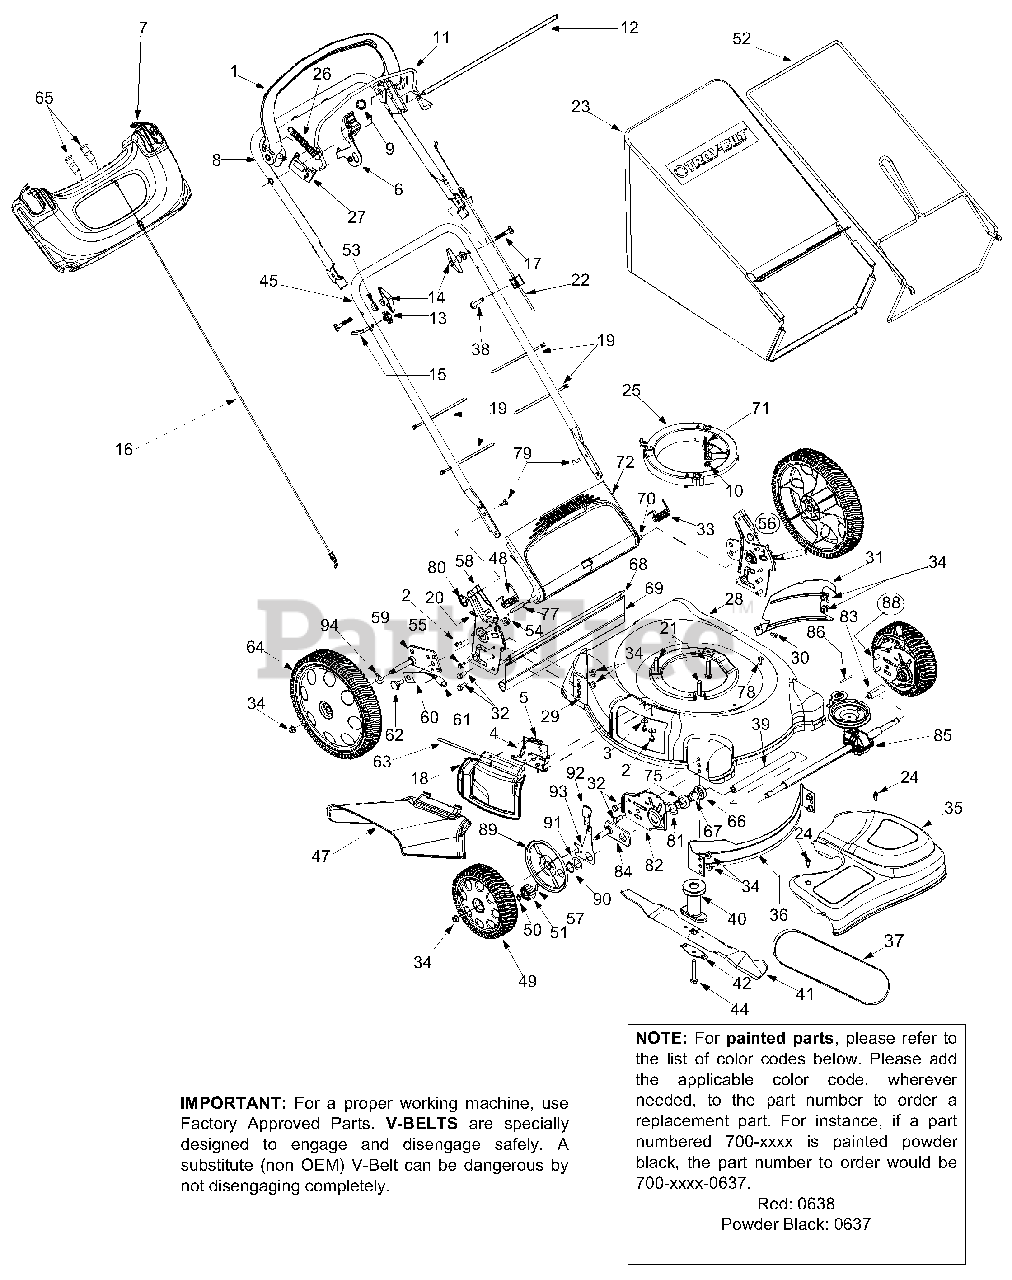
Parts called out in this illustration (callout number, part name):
1	Drive Control Bar: Red
2	TT Screw 1/4-20 x 0.5
3	Bell Washer.265 x 0.75
4	Deflector Chute Adapter
5	Torsion Spring
6	Self Start Control Assembly
7	Handle Panel
11	Blade Control Bar
12	Control Rod
13	Handle Knob
14	Handle Knob
16	Smart Speed(TM) Control Cable
17	Carriage Bolt 5/16-18 x 2.0
18	Mulch Plug Comp.
19	Cable Tie
20	Cotter Pin
21	Self-Tapping Sems Screw
22	Smart Speed(TM)/SS Fwd. Drive Cable
23	Grassbag Assembly
24	Shoulder Screw # 12 -24
25	Engine Spacer
26	Extension Spring
27	Cable Bracket
30	Screw AB: 1/4-14:.625
31	LH Rear Baffle
32	Hex Screw 3/8-16 x.75
33	Torsion Spring LH
34	Hex Nut 3/8-16
35	Transmission Cover
36	Front Baffle
38	TT-Scr. 1/4-20 x 1.25
39	Sleeve Spacer 10.1" Lg.
40	Blade Adapter w/ Pulley
41	21" Mulching Blade
42	Blade Bell Support
44	Hex Screw 3/8-24 x 2.50
47	Chute Deflector
48	Torsion Spring RH
49	Wheel 8 x 2.125
50	Snap Ring
51	Gear 14T RH FWD
51	Gear 14T LH FWD
53	Saddle Washer
54	Hex Flange Lock Nut 3/8-16
55	Tt Screw 1/4-20 x.625"
56	Handle Bracket Assembly - RH
56	Handle Bracket Assembly - LH
57	Dowel Pin
58	Handle Bracket - RH
58	Handle Bracket - LH
59	Pivot Bar RH
59	Pivot Bar LH
60	Height Adjustment Lever
61	Foam Grip
62	Shoulder Scr.500 Dia. x.434
64	Wheel, 12 x 2.125
65	Plastic Rivet
66	Bearing Retainer
67	Bearing Sleeve
68	Wire
69	Rear Trailing Shield
70	Pivot Rod
71	Belt Keeper Pin
72	Rear Discharge Door
75	Bearing Support
77	Spacer.375 x.50 x 1.02
78	Shoulder Screw 1/4-14
79	Carriage Bolt 1/4-20
81	Wave Washer
82	Height Adjuster Plate - RH
82	Height Adjuster Plate - LH
83	Slev. Spacer 2.1" Lg.
84	Pivot Plate Assembly
85	Transmission Assembly
88	Height Adjustment Assembly RH
88	Height Adjustment Assembly LH
89	Wheel Dust Cap
90	Snap Ring
92	Adjustment Knob
93	Front Lever RH
93	Front Lever LH
94	Spring Washer
